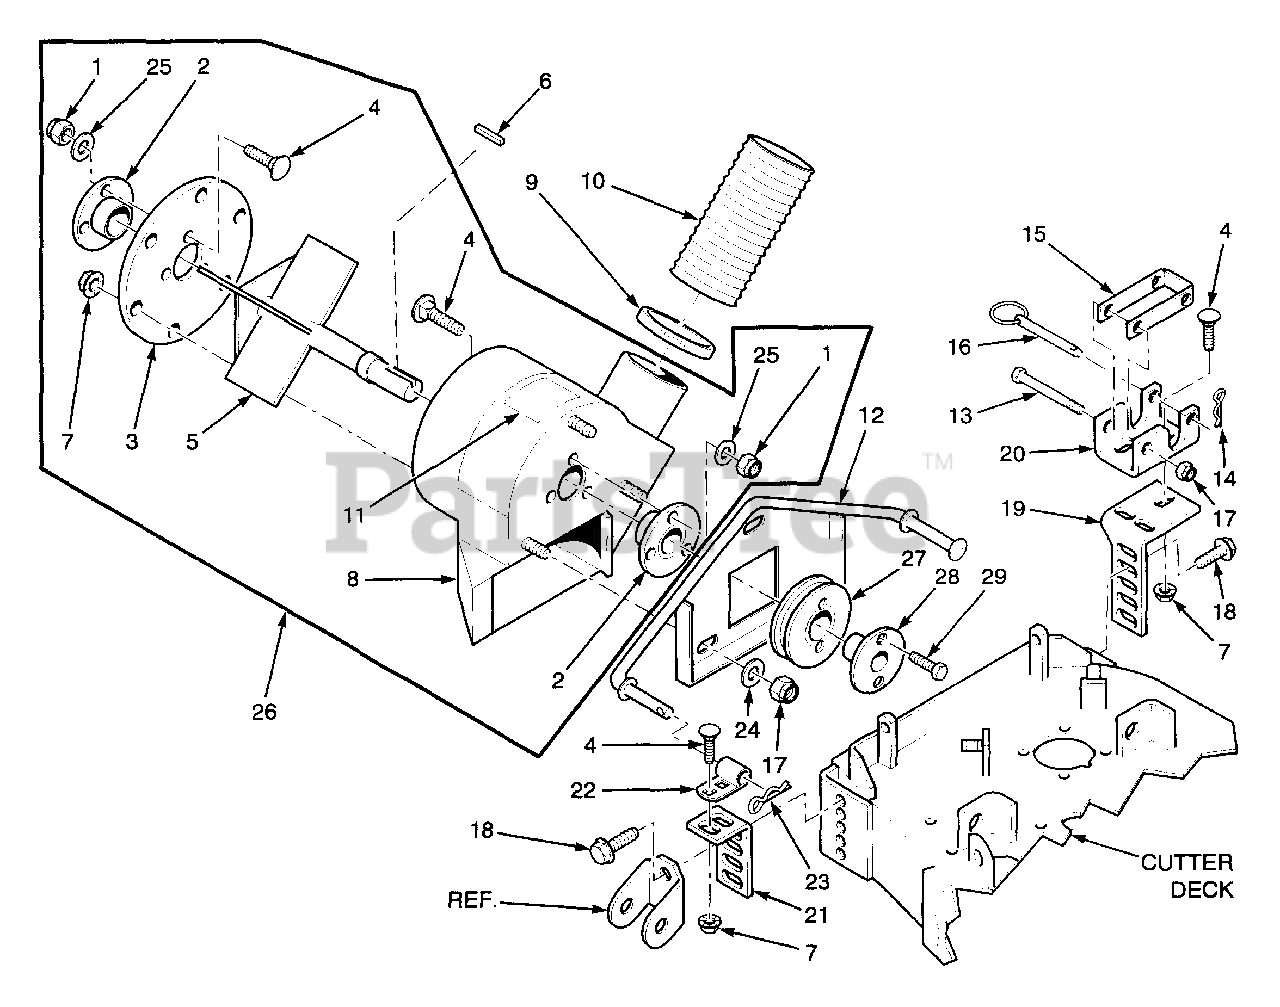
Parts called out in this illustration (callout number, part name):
1	Nut, Elastic Stop 5/16-18
2	Bearing Assembly
3	Cover, Blower Housing
4	Carriage Bolt, 5/16-18 x .75
5	Fan Weldment
6	Key, .25 x .25 x 1.50
7	Nut, Serr. Flange 5/16-18
8	Blower Housing Weldment w/Decals
9	Clamp, Hose
10	Hose, 6" x 48"
11	Decal, Danger
12	Blower Mounting Weldment
13	Bolt, Hex Head 3/8-16 x 4"
14	Hair Pin, .094 dia. x 1.62
15	Latch
16	Ring Pin
17	Nut, Elastic Stop 3/8-16
18	Capscrew, Serr. Flange 3/8-16 x 1
19	Mounting Bracket, Rear
20	Latch Plate
21	Mounting Bracket, Front
22	Mounting Weldment, Front
23	Hair Pin, .148 dia. x 2.75
24	Flat Washer, 3/8 (.391 x .938 x .105)
25	Flat Washer, 5/16 (.344 x .688 x .065)
26	Blower Housing Assembly
27	Pulley, 5.75 O.D.
28	Tapered Hub, 1.00 Bore
29	Bolt, Hex Head .25-20 x .75
